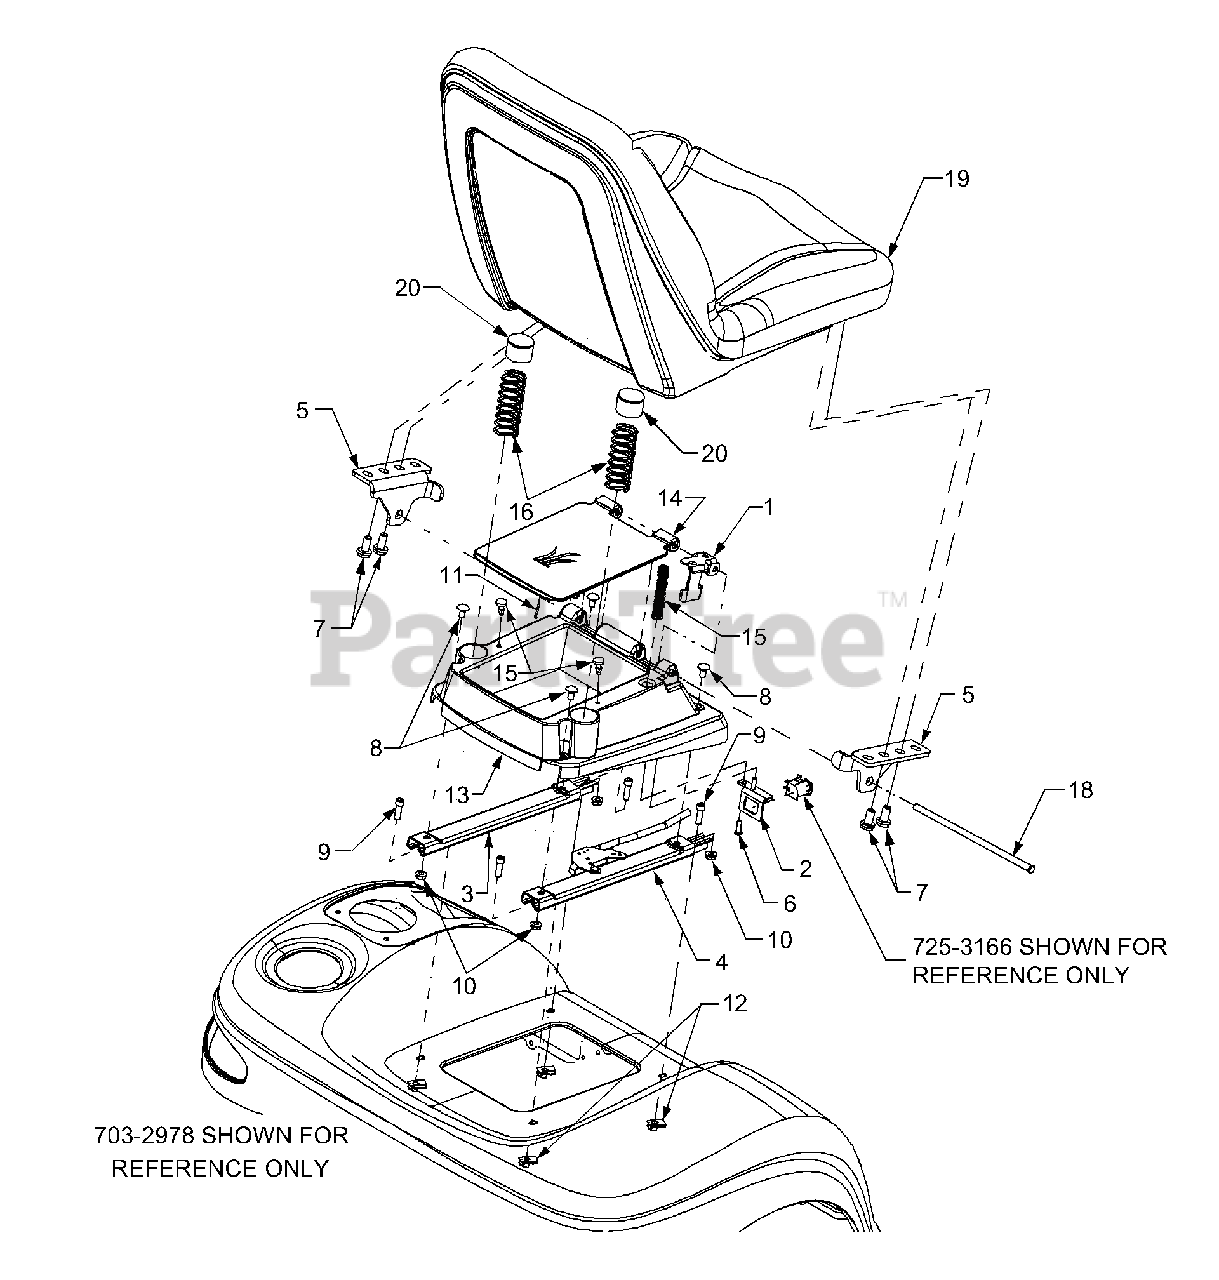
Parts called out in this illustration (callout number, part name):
1	Bracket, Seat Switch
2	Bracket, Switch Mounting
3	Track, Seat, w/o Latch
4	Track, Seat, w/Latch
7	Screw, Hex Wash. Hd. 5/16-18 x .625
8	Carriage Bolt, 5/16-18 x .62
9	Screw, Pan Torx Hd. 5/16-18 x 1.0
10	Nut, Hex Flange Lock, 5/16-18
11	Pin, Cotter, 3/32 x .75
12	Speed Nut, U-Type, 5/16-18
13	Base, Seat
14	Lid, Tlbx
15	Spring, Compression
16	Spring, Compression
18	Rod, Seat Pivot
19	Seat, High Back (Ultra)
20	Cap, Spring
